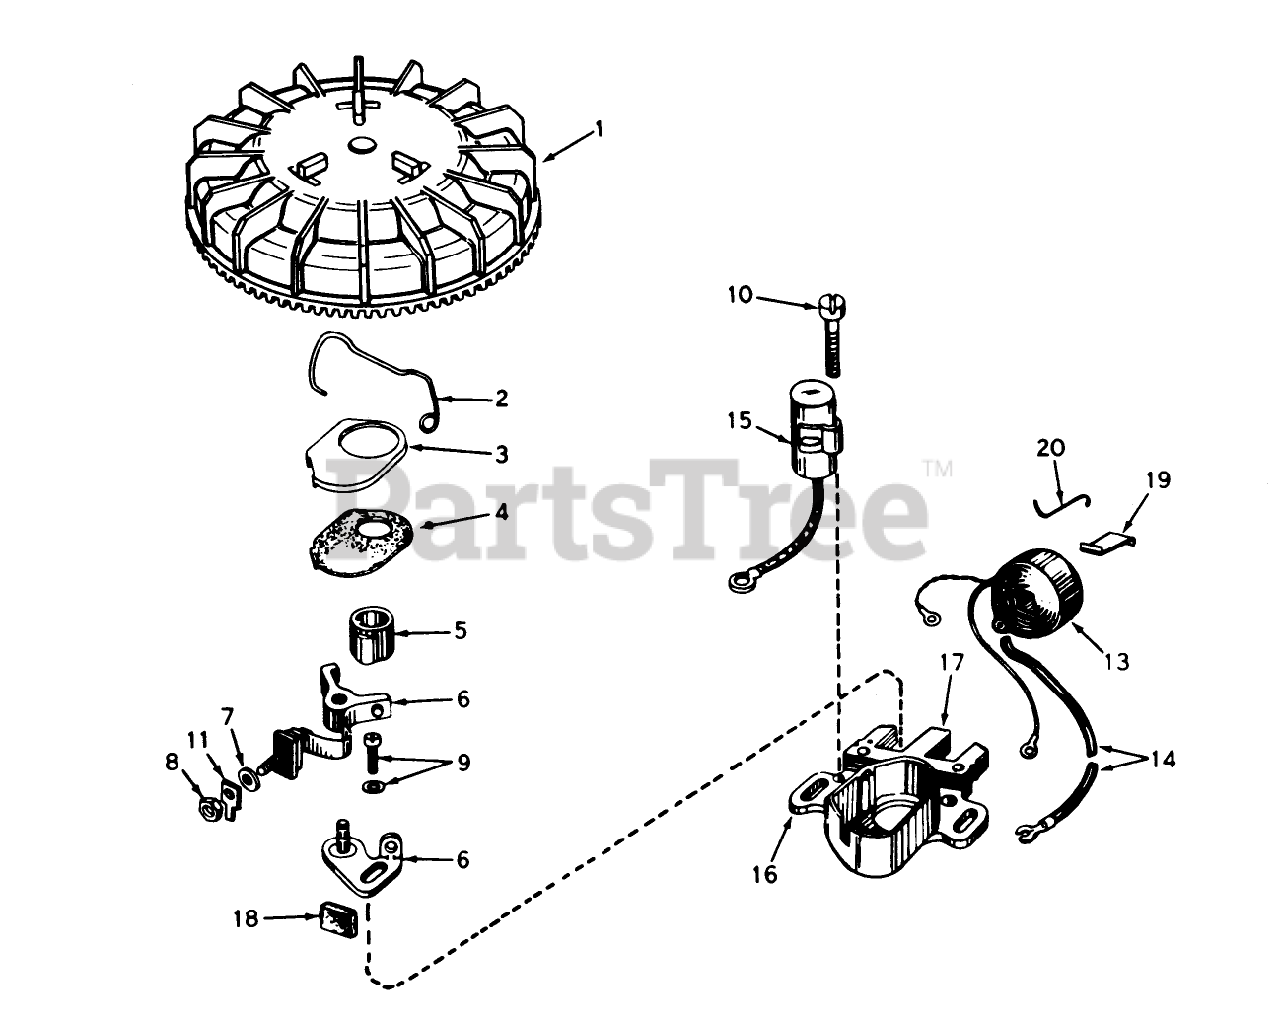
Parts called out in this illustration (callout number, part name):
1	Flywheel (Incl. Ref. #3 4)
2	Spring Breaker Box
3	Cover-Dust
4	Gasket, Dust Cover
5	Cam, Breaker
6	Breaker Assy.
7	Washer
8	DECAL
9	Breaker Screw
10	Condenser Screw
11	Terminal, Ground
13	Coil Assy. (Incl. No. 12)
14	Wire, Lead
15	Condenser
16	Core Plate
17	Stator Assy. (Incl. Ref. #2 thru 11, 13, 14, 16, 17 19)
18	Felt,Cam Wiper
19	Spring Coil Wedge
20	Clip, Coil
